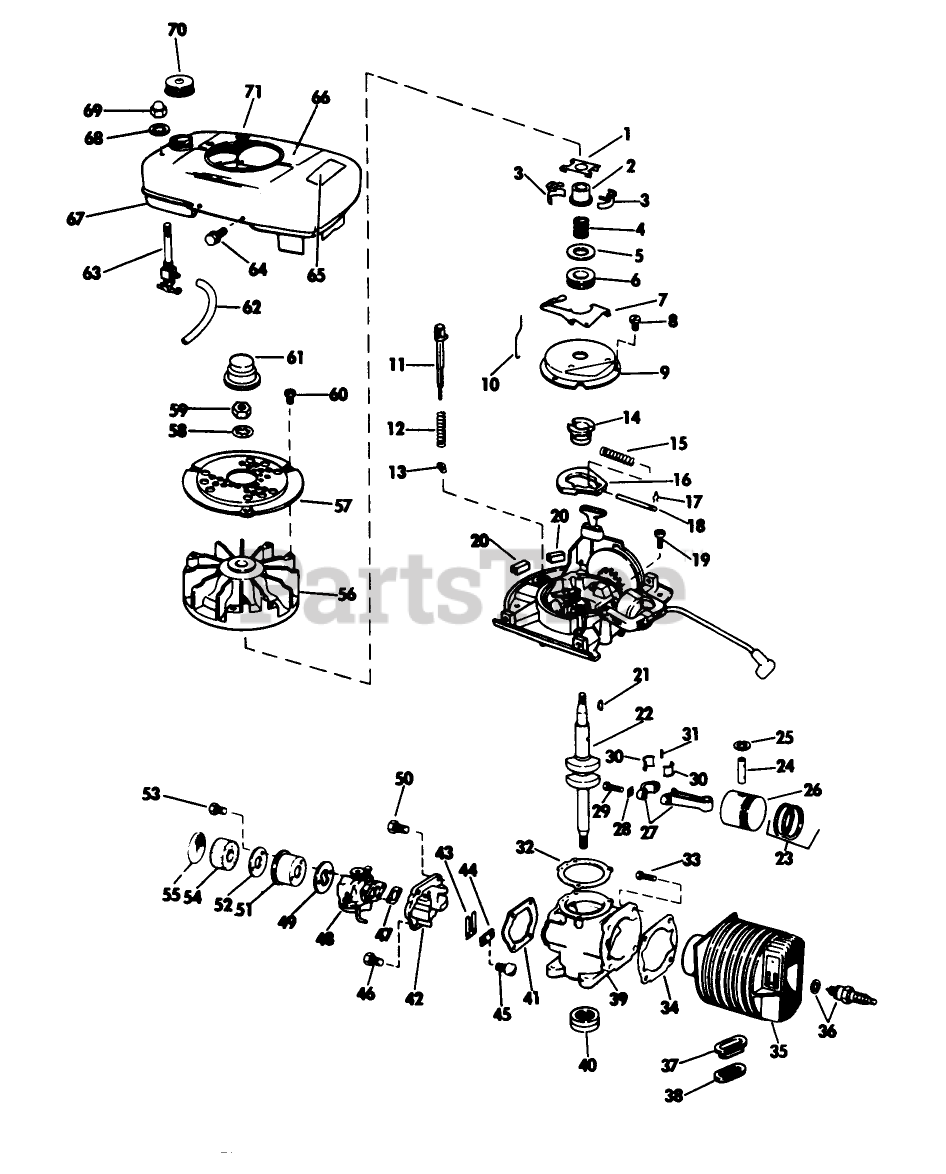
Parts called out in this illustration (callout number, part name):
2	COLLAR S
6	THRUST COLLAR S
7	LEVER-GOVERNOR S
8	SCREW S
9	DUST COVER S
12	SPRING S
14	SPARK ADV. S
15	SPARK ADV. SPRING S
16	FLYWEIGHT S
17	SPARK ADJ. SPRING
18	PIN,SPARK ADV. S
25	RING-RETAINING
30	LINER ASM
32	GASKET S
34	GASKET S
38	GASKET S
44	PLATE-BACKUP, REED
46	SCREW S
47	GASKET S
49	GASKET S
50	SCREW S
52	BACK-UP PLATE
54	ELEMENT
63	VALVE&SCREEN SM
64	SCREW S
69	PALNUT S
